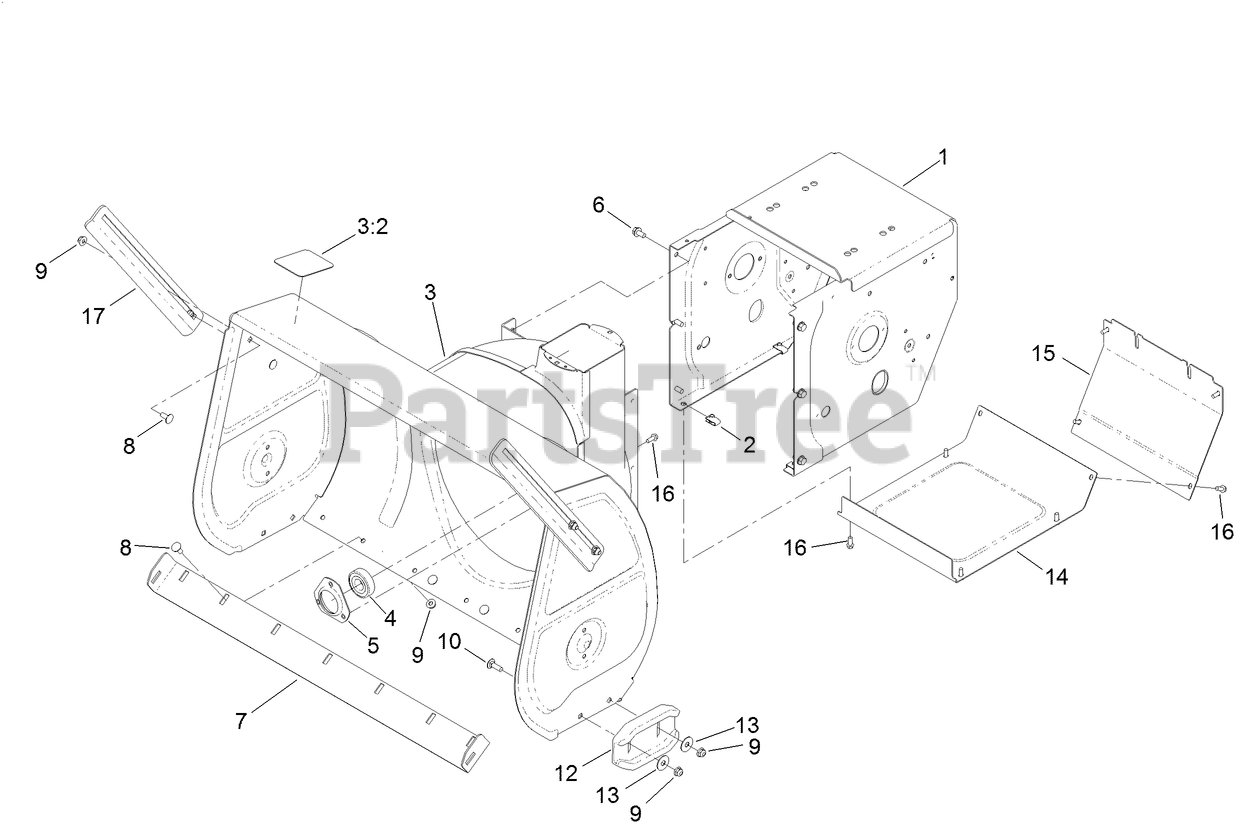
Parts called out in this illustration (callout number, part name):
1	FRAME-TRACTION
3	AUGER HOUSING ASM
3:2	DECAL-DANGER, AUGER
4	BEARING-BALL
5	RETAINER-BEARING
6	SCREW-HWHTF
7	BLADE-SCRAPER
8	BOLT-CARR
9	NUT-HF
10	BOLT-CARR
12	SKID-CAST
13	WASHER-FLAT
14	COVER-BOTTOM
15	COVER-REAR
16	SCREW-HWH
17	BREAKER-DRIFT, SIDE
